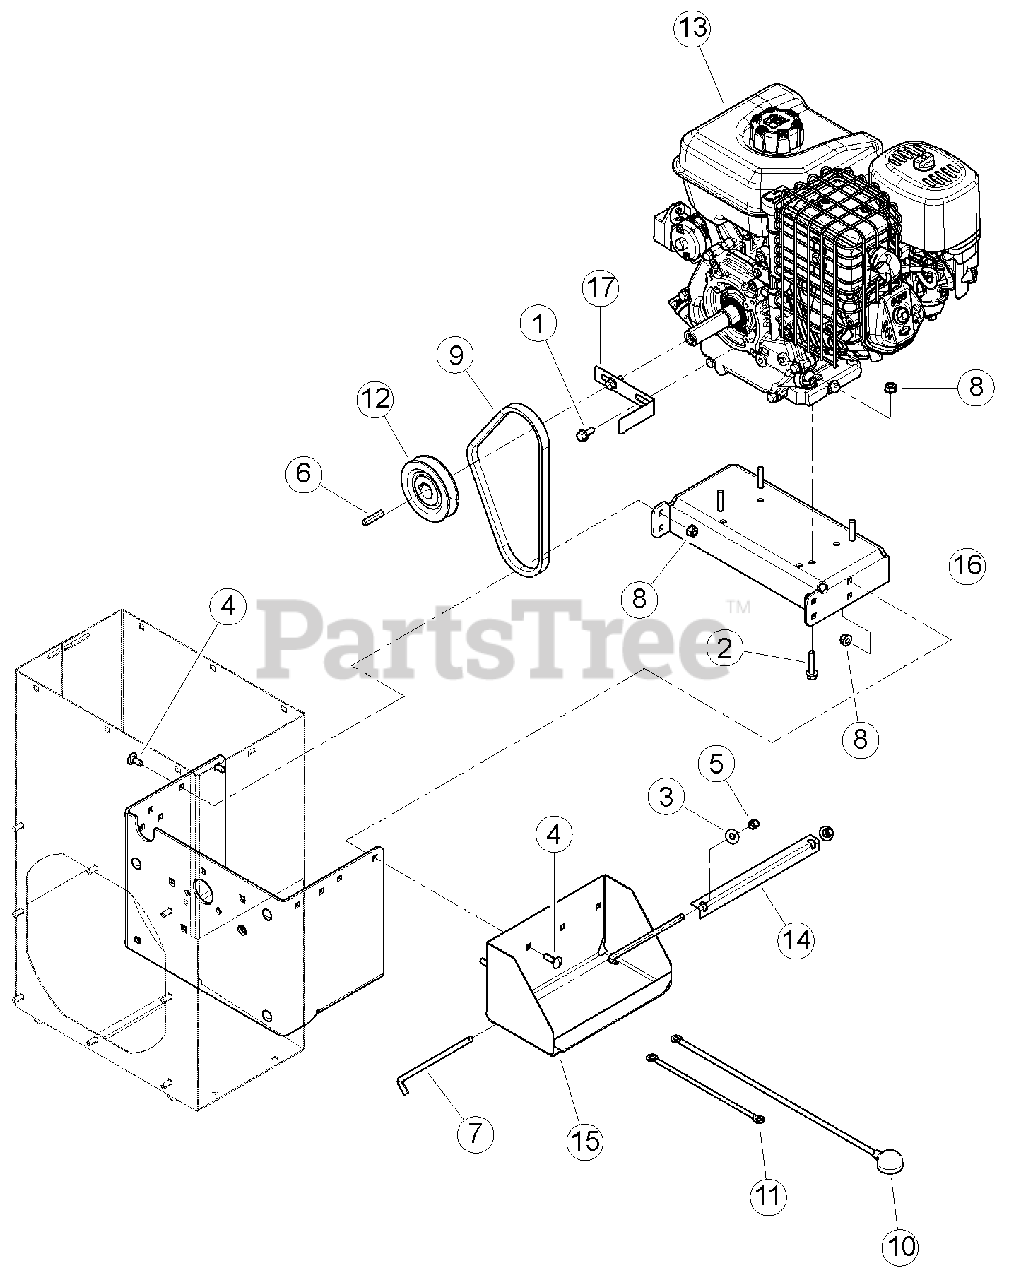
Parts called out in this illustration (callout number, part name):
1	BOLT, 5/16 X 3/4 SERRATED FLANGE NF
2	BOLT, 5/16 X 1-1/2 FLANGE NC
3	WASHER, 5/16 FLAT ZP (SC3305E ONLY)
4	BOLT, 5/16 X 1 CRG GR5 ZP (SC3305E ONLY)
5	NUT, 5/16 NE NYLOCK ZP (SC3305E ONLY)
6	KEY, 1/4 SQUARE X 1-1/2 LONG PLAIN
7	BOLT, 5/16 X 8-3/4 L-TYPE BATTERY (SC3305E ONLY)
8	NUT, 5/16-18 NYLOCK-FLANGE
9	BELT, 29" C/S
10	CABLE, 33" POS - R/R WITH BOOT (SC3305E ONLY)
11	CABLE, 9" NEG - R/R (SC3305E ONLY)
12	PULLEY, CAST 4" OD 1" BORE B GRV
13	ENGINE, 306CC B&S HORIZONTAL ELECTRIC
13	ENGINE, 306CC B&S HORIZONTAL
13	ENGINE, 900 SERIES B&S HORIZONTAL
14	ANGLE, BATTERY HOLD DOWN (SC3305E ONLY)
15	WELDMENT, BATTERY BOX (SC3305E ONLY)
16	PLATE, ENGINE MOUNTING
17	GUIDE, BELT
